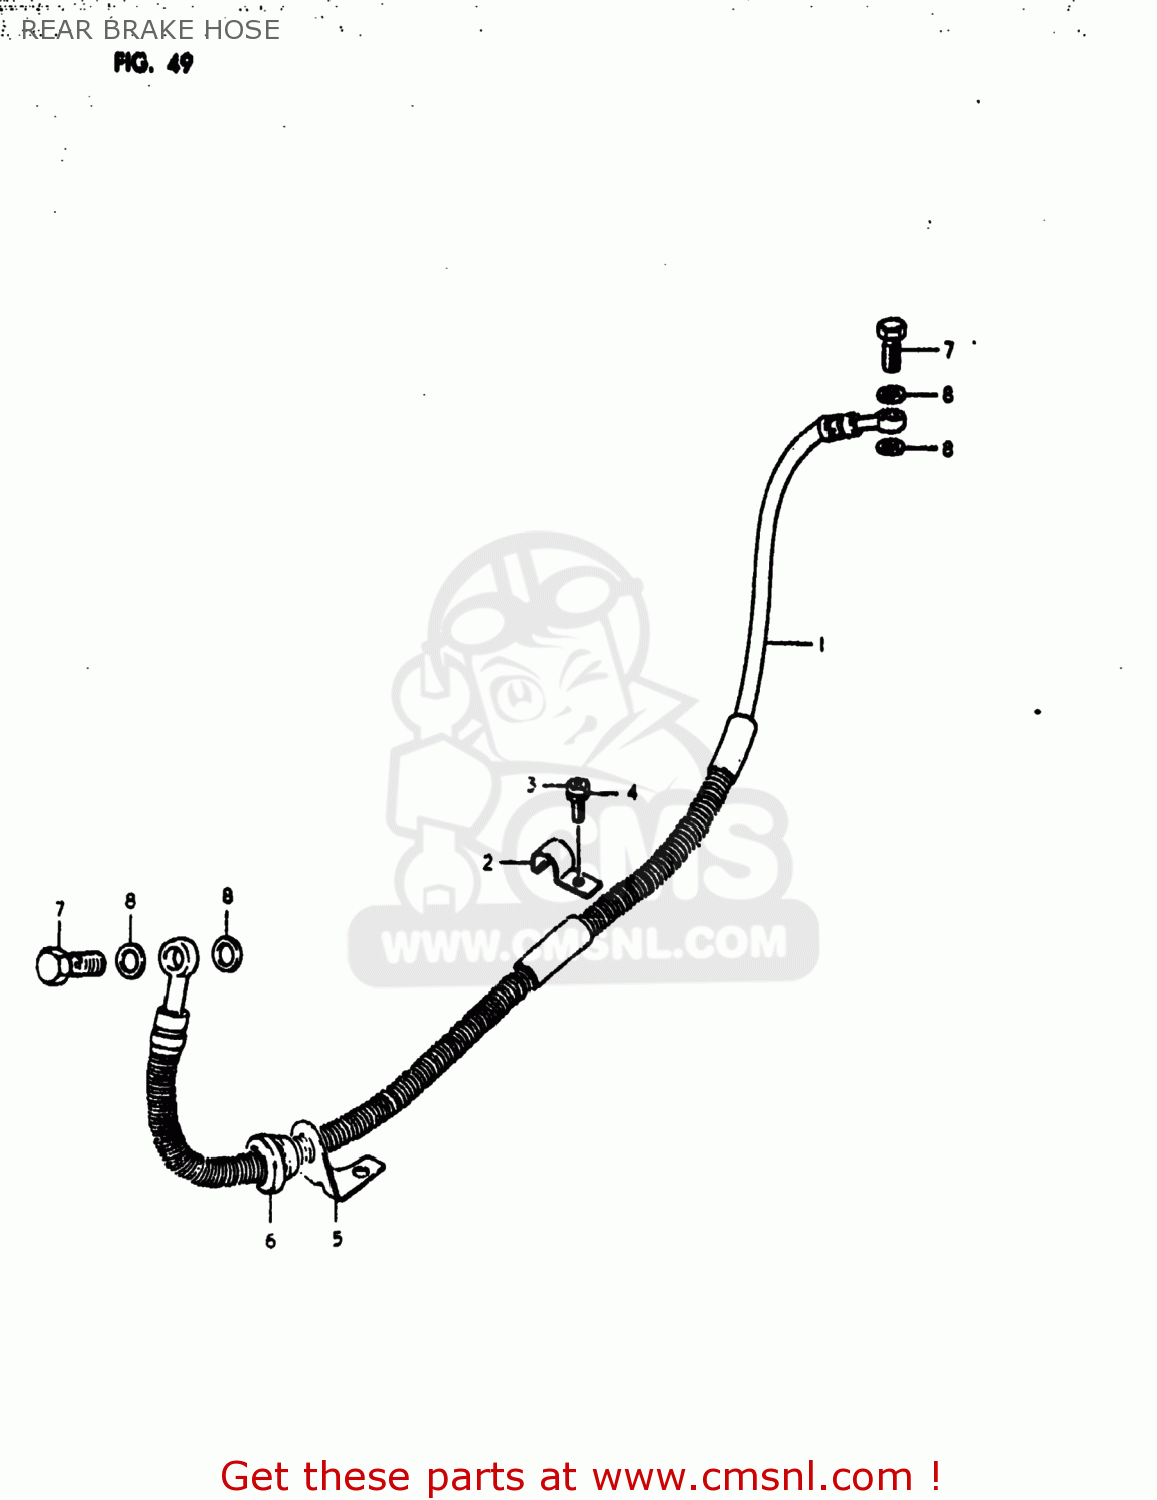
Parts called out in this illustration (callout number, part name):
1	HOSE,REAR BRAKE
2	CLAMP,REAR BRAKE HOSE
3	SCREW(6X8)
4	LOCK WASHER
5	GUIDE,BRAKE HOSE
6	GROMMET,BRAKE HOSE GUIDE
7	BOLT,UNION
8	WASHER
